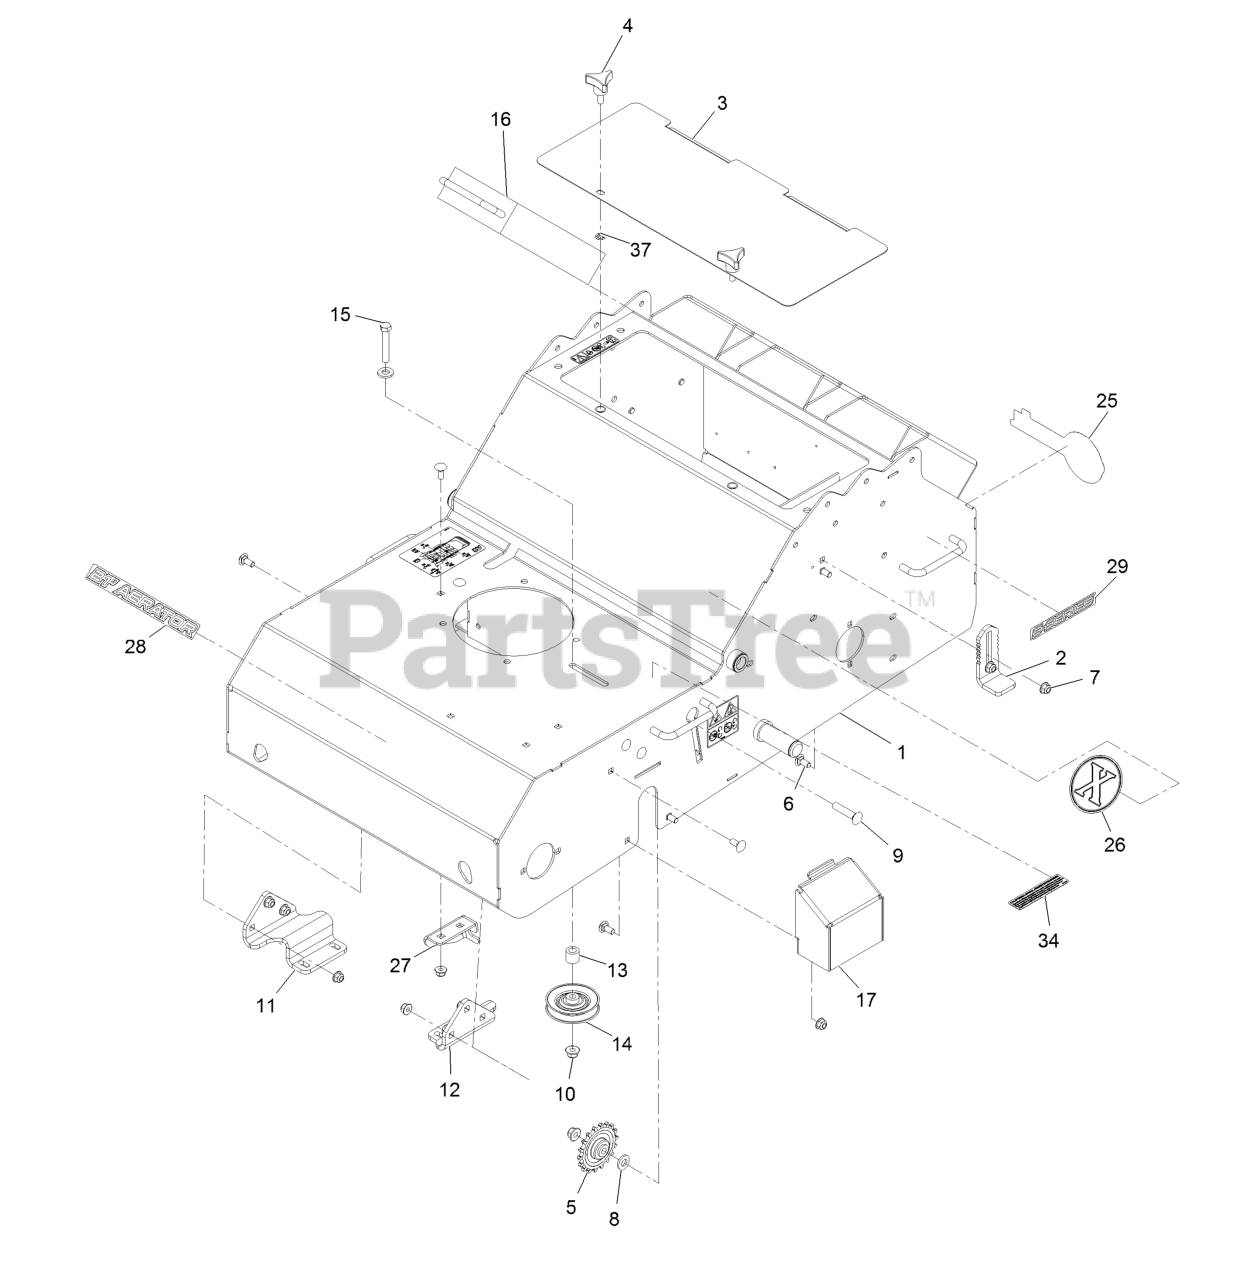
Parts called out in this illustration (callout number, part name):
1	Frame ASM
2	Stop-Depth
3	Cover-Access
4	Knob-5/16X3/4 3-Prong
5	Sprocket-Idler
6	Bolt-Carriage 5/16-18 X 3/4
7	Nut-Nyloc 5/16-18 Flg
9	Bolt-Carriage 3/8-16 X 1 3/4
10	Nut-Nyloc 3/8-16 Flg
11	Bracket-Mount Axle, RH
12	Bracket-Mount Axle, LH
13	Bushing-Idler
15	Screw-HH 3/8-16 X 2 1/4
16	Weight-Aerator
17	Cover-Transaxle
25	Decal, Exmark Logo
26	Decal-X-Logo
27	Bracket-Mounting, Cable
28	Decal-Aerator 21 Logo
29	Decal-S-Series
34	Decal-Arrester, Spark
37	Nut-Push
